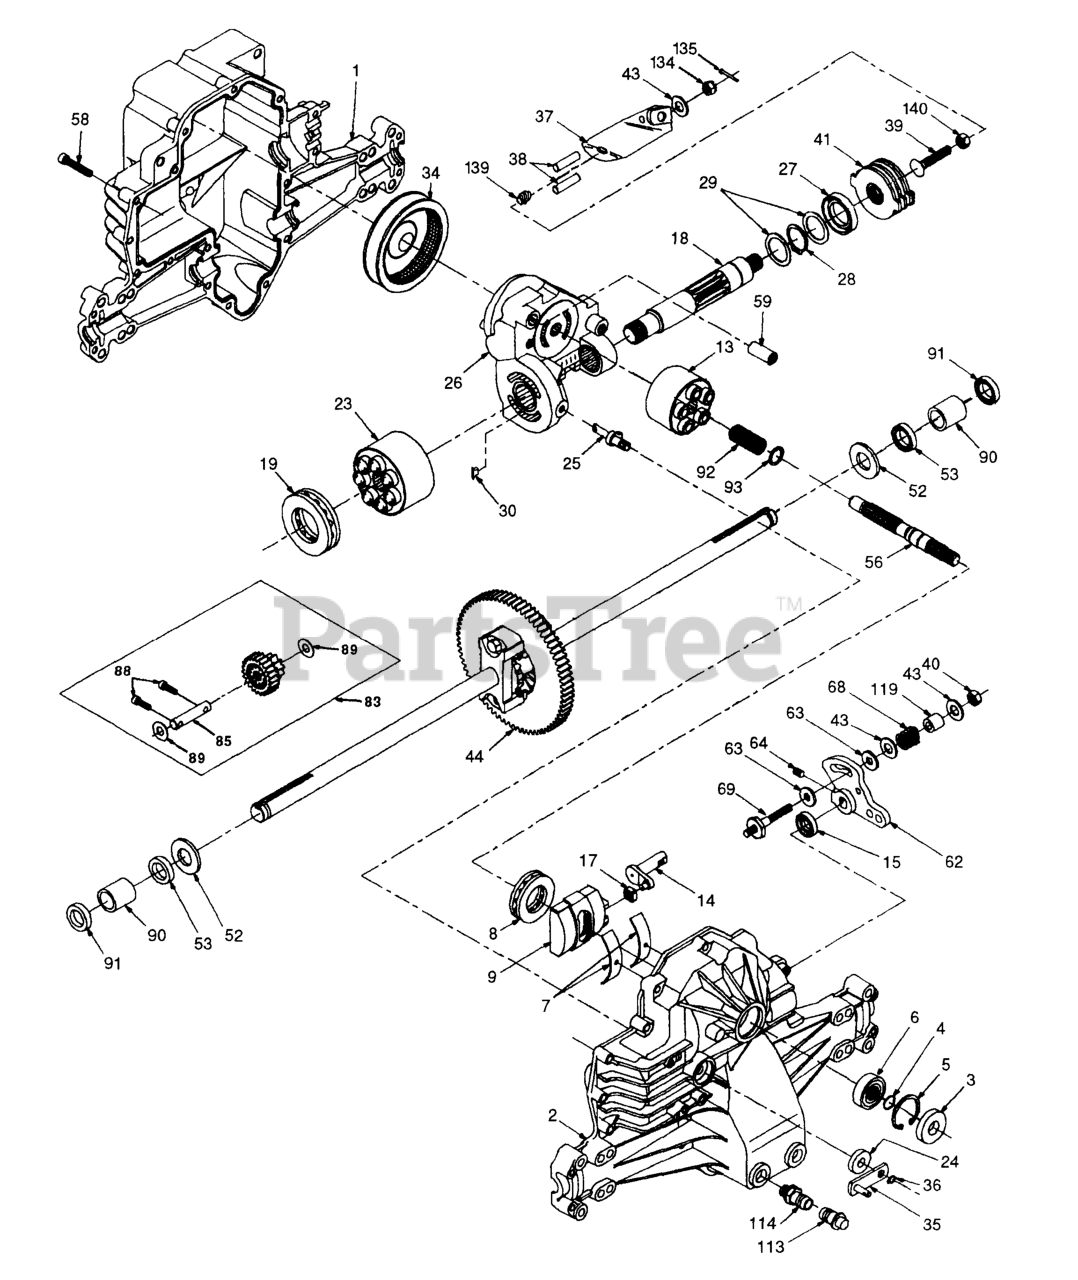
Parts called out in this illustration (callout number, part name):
1	LOWER HOUSING
2	HOUSING UPPER 70255
3	SEAL.LIP.H-G.(9008000-0128)
4	RING RETAINING 2003016
5	RING.RETAINING.(2003052)
6	BALL BEARING
7	CRADLE BEARING
8	BEARING, THRUST 50551
9	SWASHPLATE (2003087)
13	BLOCK, CYL ASSY
14	TRUNNION ARM
17	SLOT GUIDE
18	SHAFT, MOTOR
19	BEARING, THRUST 50552
23	BLOCK, CYL ASSY
25	BYPASS ACTUATOR
26	CENTER SECTION ASS'Y KIT
28	RETAINING RING
34	ELEMENT, OIL FILTER
35	BYPASS ARM
36	RETAINING RING 44870
37	ACTUATING ARM
38	ACTUATING PIN 44891
39	BOLT 5/16-24 X 1-3/4
40	LOCKNUT, HEX 5/16-24
41	BRAKE ROTOR 70135 HYDRO-GEAR
43	WASHER .34X.88X.06.44130
44	KIT SVC DIFFRENTIAL 70130
52	WASHER.HYDRO-GEAR 44875
53	SEAL.HYDRO.53901
56	SHAFT.INPUT.50005
58	BOLT #44876
62	CONTROL ARM 50254
63	DAMPENER PUCK
64	SCREW.SET.50018
68	SPRING HELICAL COMP 50277
69	STUD 5/16-24 50284
83	JACK SHAFT ASSY
89	WASHER 50132
90	SLEEVE.BEARING 50118
91	RP SEAL, WIPER
92	SPRING 2003014
113	CAP, VENT ASSY
114	O-RING KIT 70110
119	SPACER.HYDRO GEAR 50278
134	NUT.CAS.HYD.44142
135	ID DOT HYDD
139	SPRING, COMPRESSION 50431
140	NUT, HEX 5/16-24
